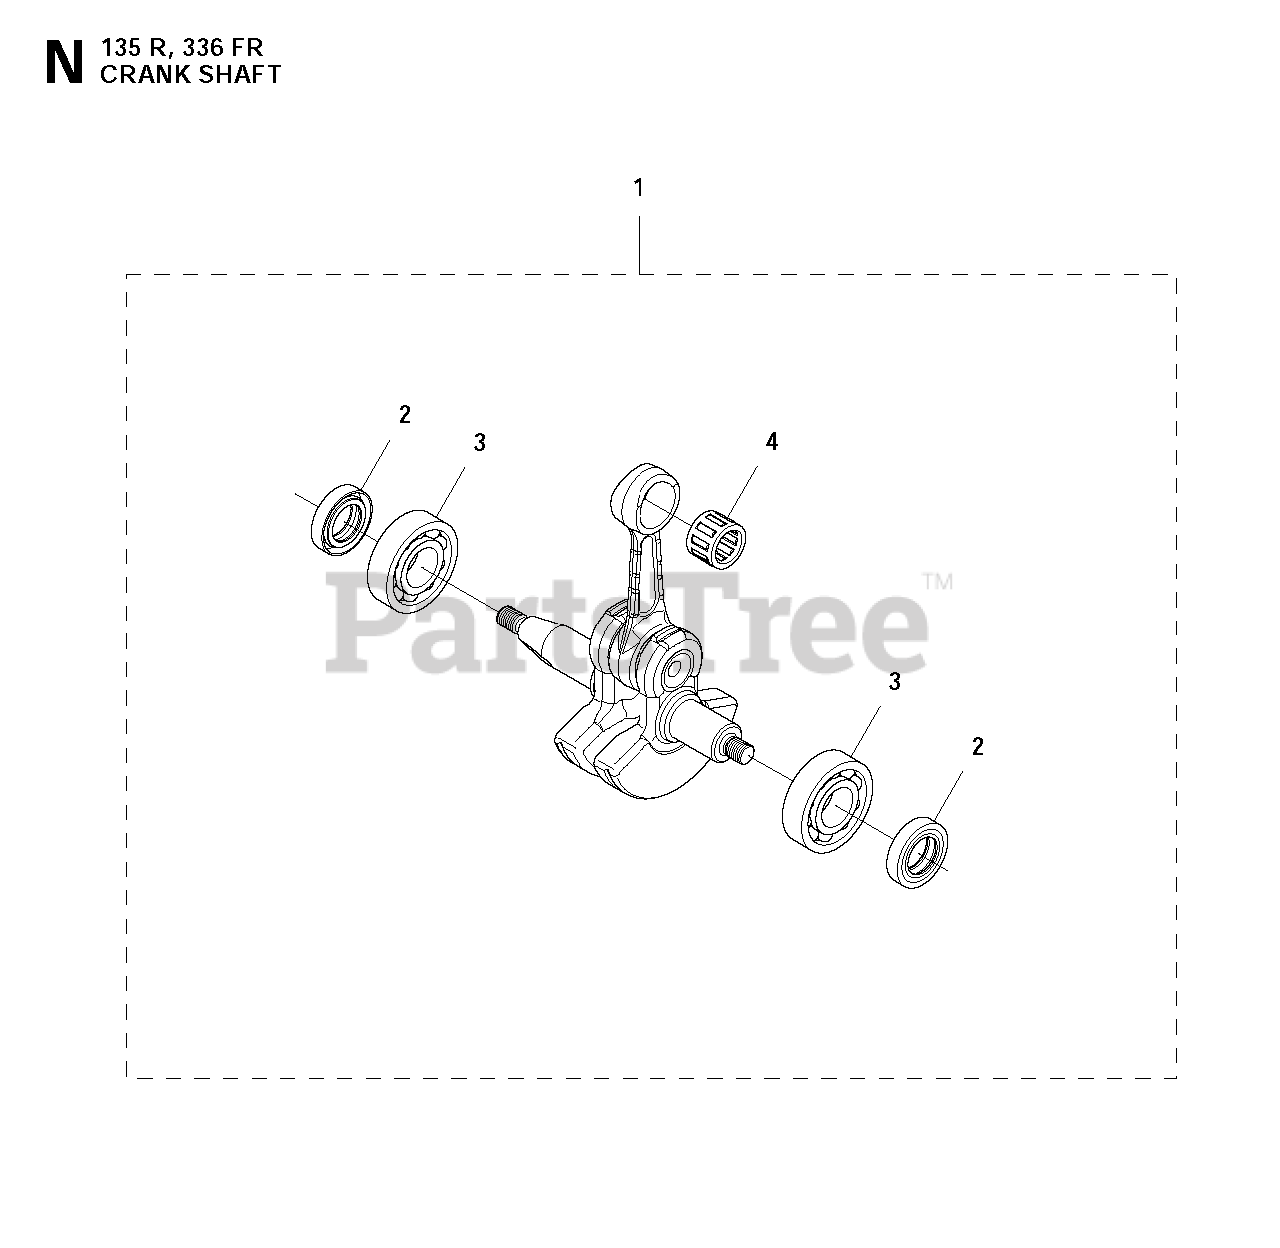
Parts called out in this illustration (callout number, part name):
1	CRANKSHAFT
2	SEALING RING
3	BALL BEARING
4	SUPPORT BUSHING
